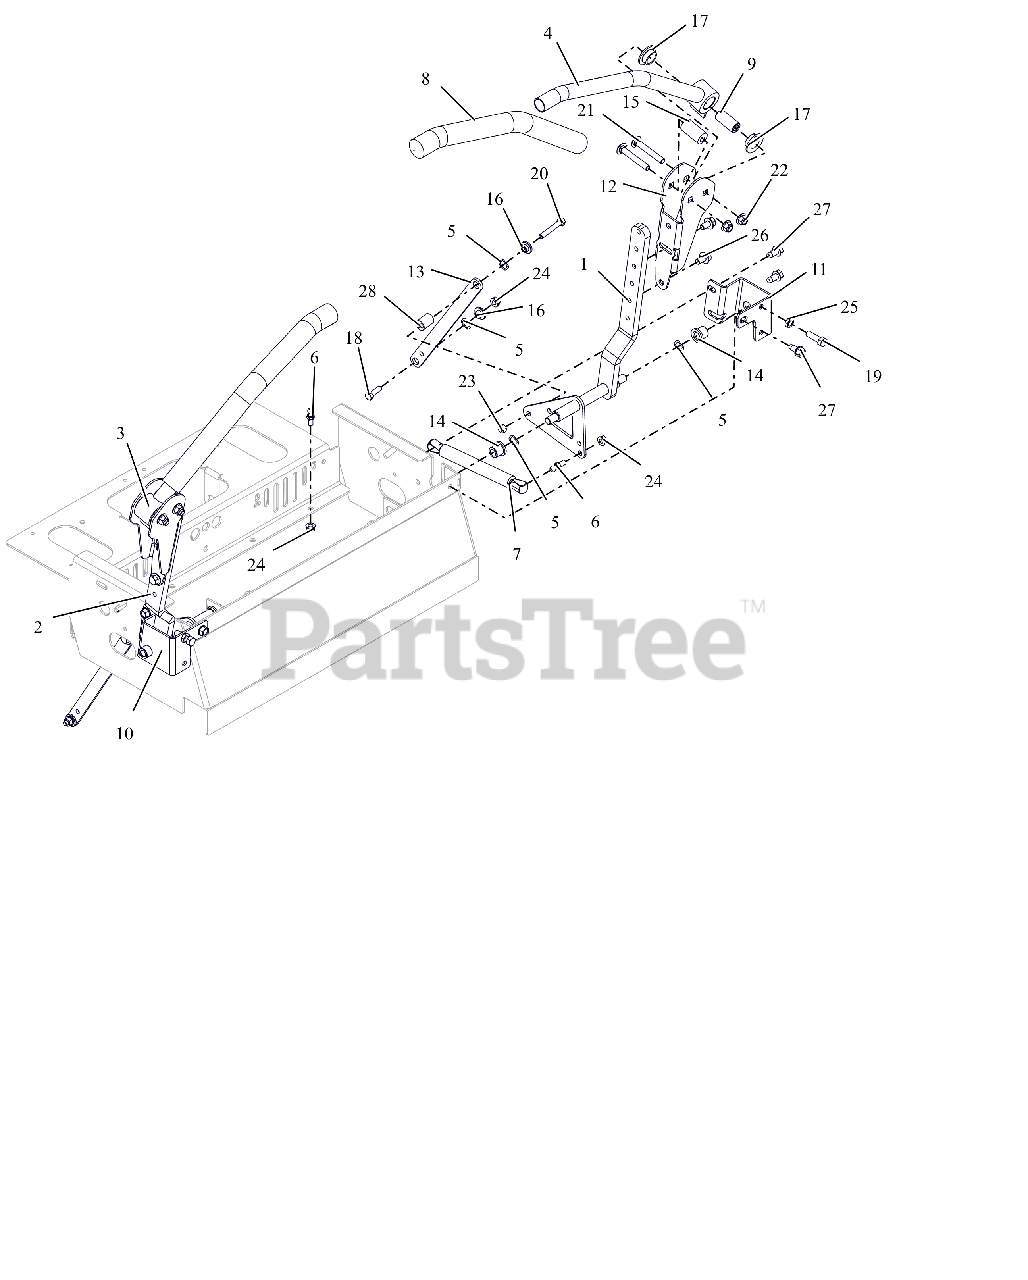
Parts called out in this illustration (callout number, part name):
1	WLDMT, LH LOWER CONTROL ARM
2	WLDMT, RH LOWER CONTROL ARM
3	WLDMT, CONTROL HANDLE- BLK
4	WLDMT, CONTROL HANDLE- BLK
5	WAVE WASHER .531X.781X.125FH
6	STUD- BALL
7	DAMPER
8	GRIP, HANDLEBAR
9	SPACER, STEERING ARM
10	PT200/400 RH CNTRL STP BRK-RED
11	PT200/400 LH CNTRL STP BRK-RED
12	ADJ UPPER CONTROL ARM BRKT-BLK
13	LINK, STEERING CONTROL
14	BHSG-FLG .500X.750X.750X.125
15	BSHG, ECCENTRIC.406X.875X1.625
16	BSHG-FLG .32X.500X.344X.880
17	BSHG-FLG .762X1.48X.44 NYL
18	BLT,HEX .31-18X1.00 G5 ZCC
19	BLT, HEX .38-16X1.25 G5 ZCC
20	BLT, HEX .31-18X2.00 G5 ZCC
21	BLT, RHSSN.38-16X2.50 G5 ZCC
22	NUT,NYL-FLG .38-16 GF ZCC
23	NUT,LK-CTR .31-18 GA ZCC
24	NUT-LK-TOP-FLG .312-18 GF ZCC
25	NUT-JAM .375-16 G2 ZCC
26	BLT, SERHFWH .38-16X.625 ZCC
27	SCR,TAP .375-16X.75 HWH TR ZCC
28	ECCENTRIC
